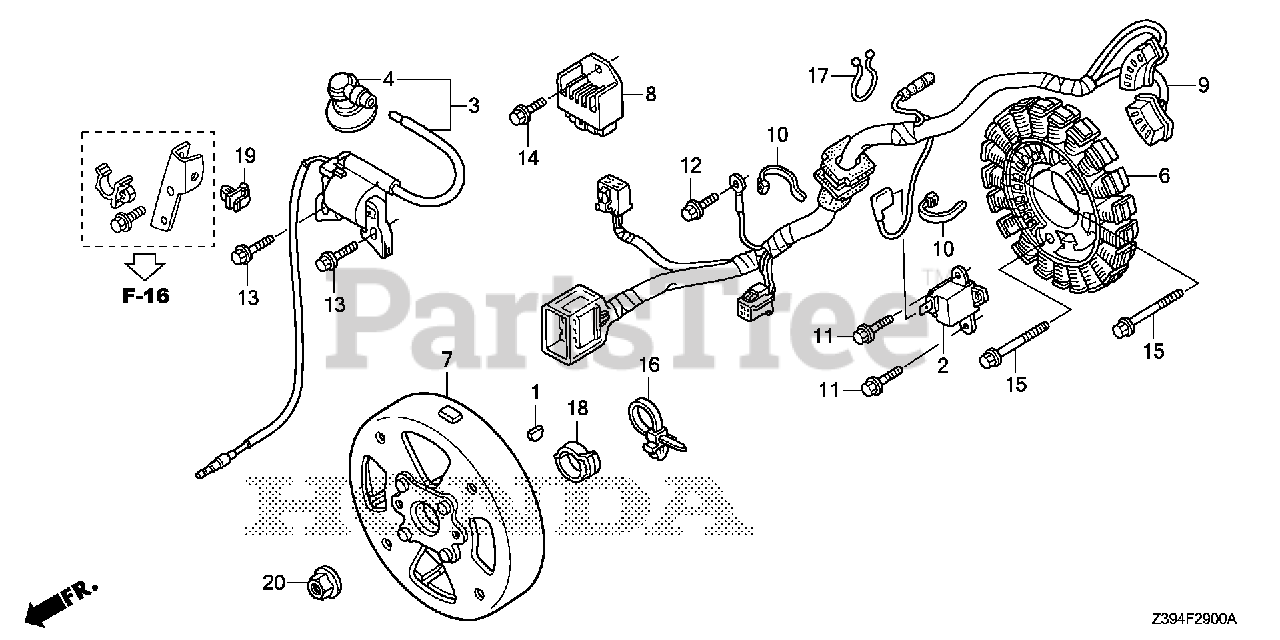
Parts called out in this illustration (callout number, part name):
1	KEY, SPECIAL
2	GENERATOR, PULSE
3	COIL ASSY., IGNITION
4	CAP ASSY., NOISE SUPPRESSOR
8	RECTIFIER ASSY.
9	WIRE HARNESS ASSY., GENERATOR
10	BAND, NYLON
11	BOLT, FLANGE (5X14) (CT200)
12	BOLT, FLANGE (5X10) (CT200)
13	BOLT, FLANGE (6X20) (CT200)
14	BOLT, FLANGE (6X16) (CT200)
15	BOLT, FLANGE (5X32) (CT200)
16	BAND, WIRE HARNESS (150MM) (BLUE)
17	BAND, TUBE
18	CLIP, WIRE HARNESS
19	CLIP, WIRE HARNESS
20	NUT, FLANGE (12MM)
